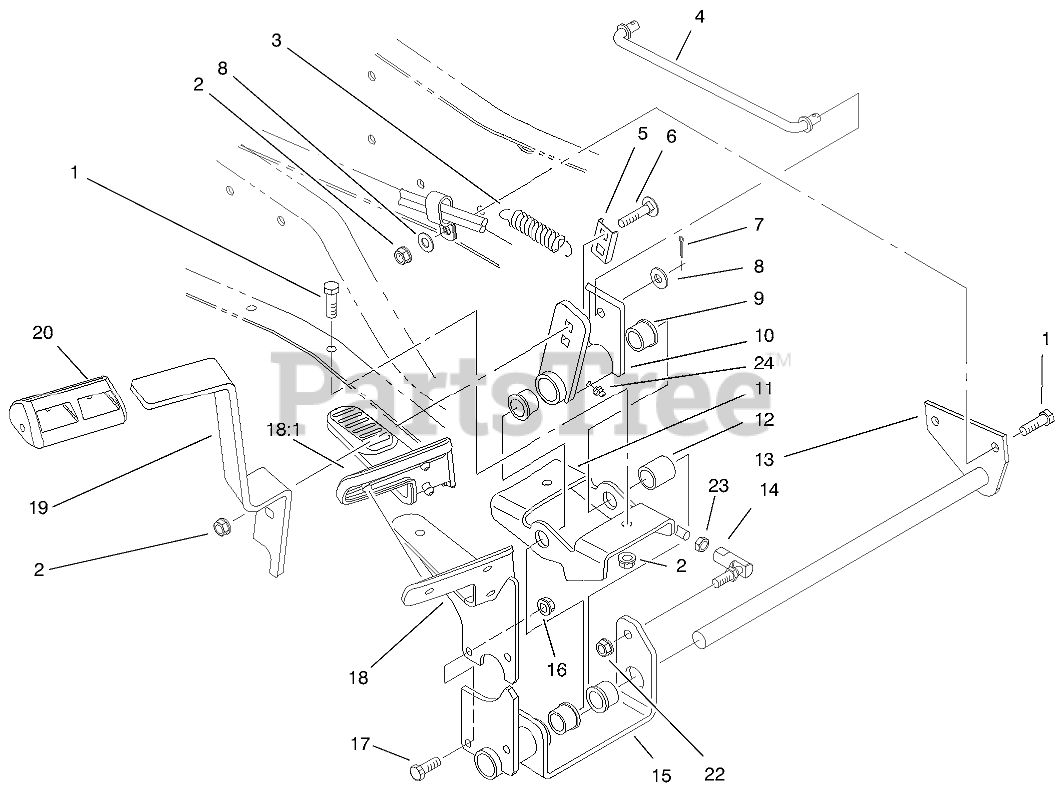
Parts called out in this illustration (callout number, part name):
1	SCREW-HH
2	NUT-LOCK, NI
3	SPRING-IDLER
4	ROD-PIVOT PLATE TO PEDAL
5	RETAINER-SCREW
6	BOLT-CARR
7	PIN-COTTER
8	WASHER-FLAT
9	BUSHING-FLANGE
10	Bracket-Brake
11	BRACKET-SUPPORT
12	SPACER-PEDAL
13	SHAFT-PIVOT
14	END-TIE ROD, RH
15	BRACKET-FOWARD/REVERSE
16	NUT-LOCK, NI
17	SCREW-HH
18	ASSEMBLY - HYDRO PEDAL
18:1	PAD - HYDRO PEDAL
19	PEDAL-BRAKE
20	PAD-PEDAL, BRAKE
22	NUT-LOCK
23	NUT-HJ
24	FITTING-GREASE
